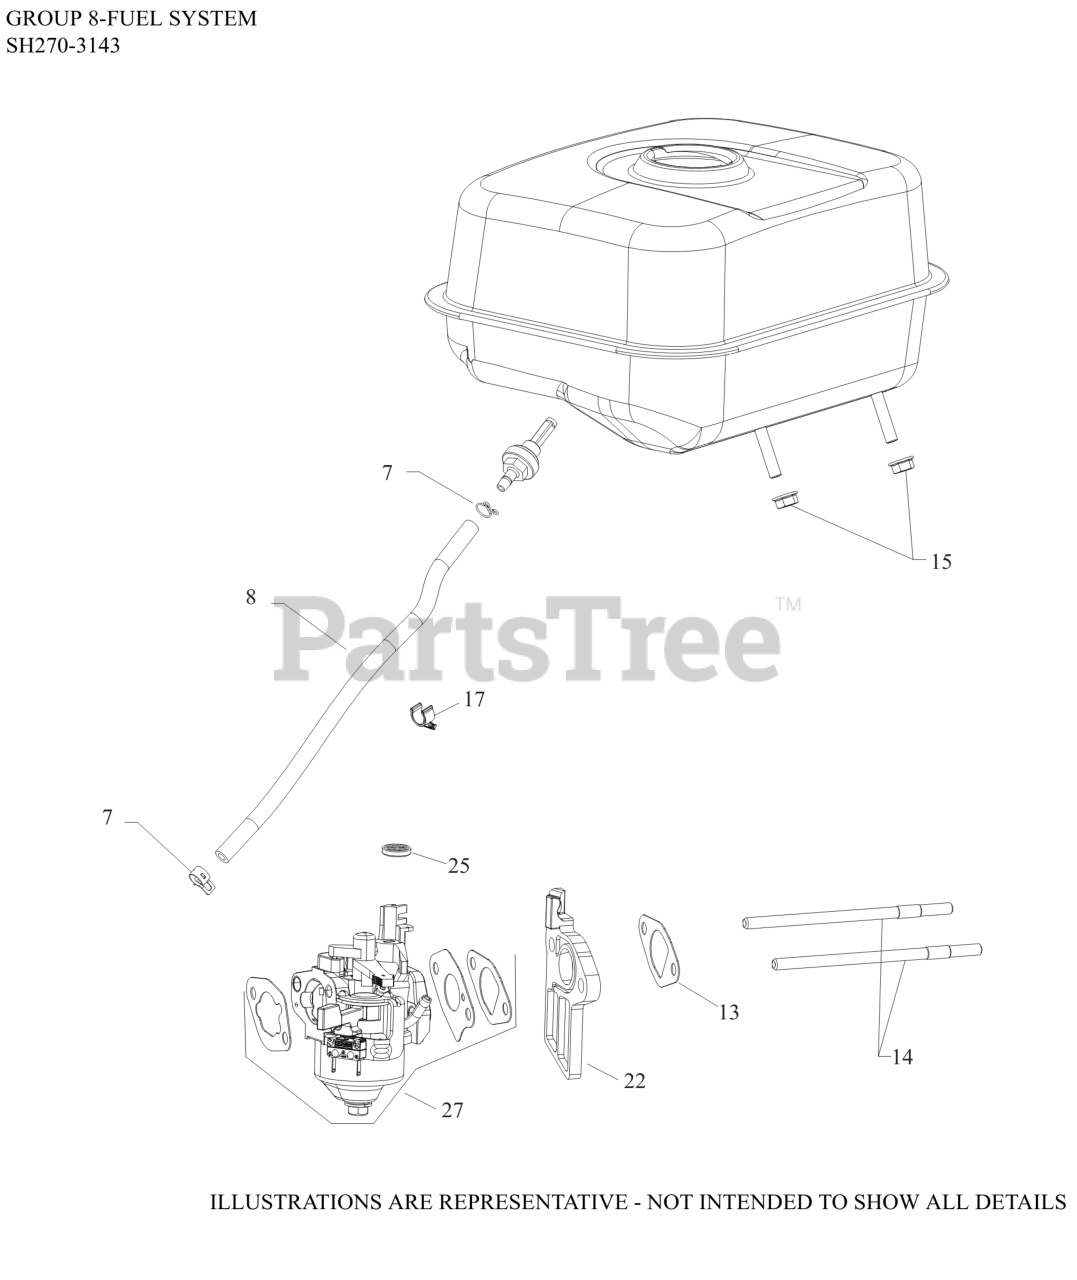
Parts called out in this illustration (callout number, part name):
7	CLAMP, FUEL LINE
8	LINE, FUEL (10"-CUT TO LENGTH)
13	KIT, INTAKE GASKET
14	STUD, CARBURETOR
15	NUT, HEX FLANGE (M6) - USE 14 100 16-S
17	CLIP, FUEL HOSE
22	INSULATOR, CARBURETOR
25	SEAL, INLET VALVE
27	KIT,CARB (HUAYI)
NI	KIT, CARBURETOR REPAIR (HUAYI)
NI	KIT, HIGH ALTITUDE (4,000-8,000 FT)
NI	KIT, HIGH ALTITUDE (ABOVE 8,000 FT)
